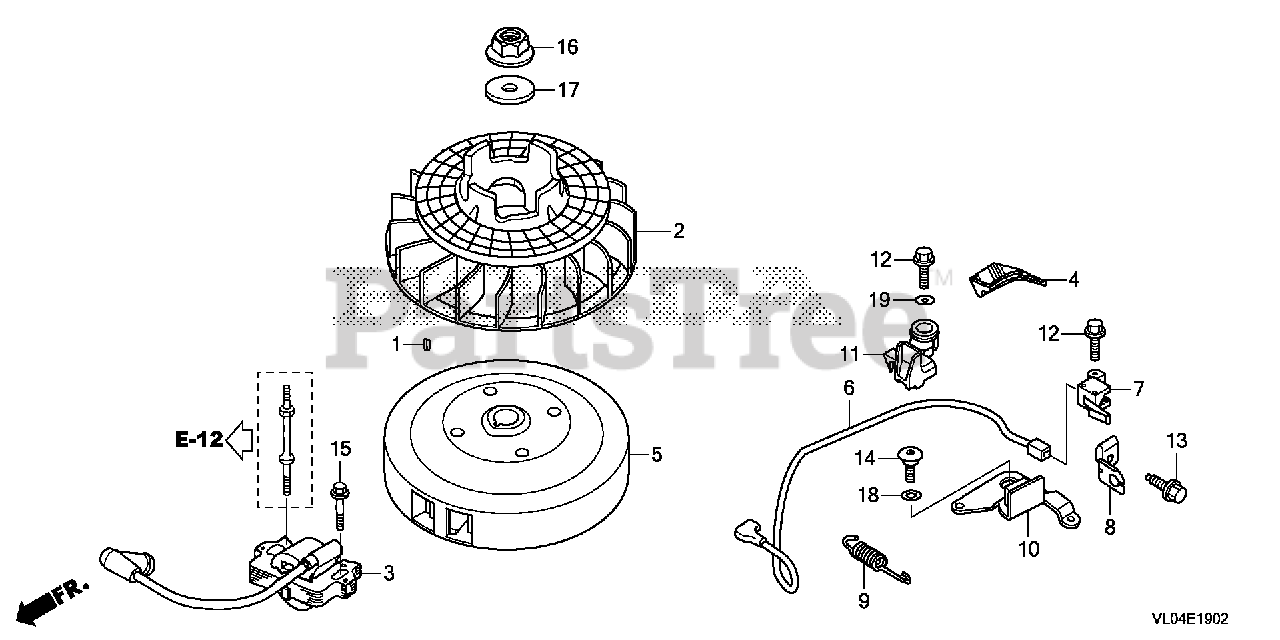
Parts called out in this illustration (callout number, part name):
1	KEY, SPECIAL WOODRUFF (25X18)
2	FAN, COOLING
3	COIL ASSY., IGN
3	COIL ASSY., IGNITION (PHELON)
4	CLAMP, WIRE
5	FLYWHEEL (FENGLONG)
6	WIRE, STOP SWITCH
7	SWITCH ASSY., ENGINE STOP
8	BRACKET, BRAKE CABLE
9	SPRING, BRAKE LEVER
10	ARM, BRAKE
11	SPRING, TENSIONER
12	BOLT, SPECIAL (5X16)
13	BOLT, FLANGE (6X14)
14	BOLT, SPECIAL
15	BOLT, FLANGE (6X23)
16	NUT, SPECIAL (14MM)
17	WASHER (14X45)
18	WASHER, SPECIAL
19	WASHER, PLAIN (5MM)
